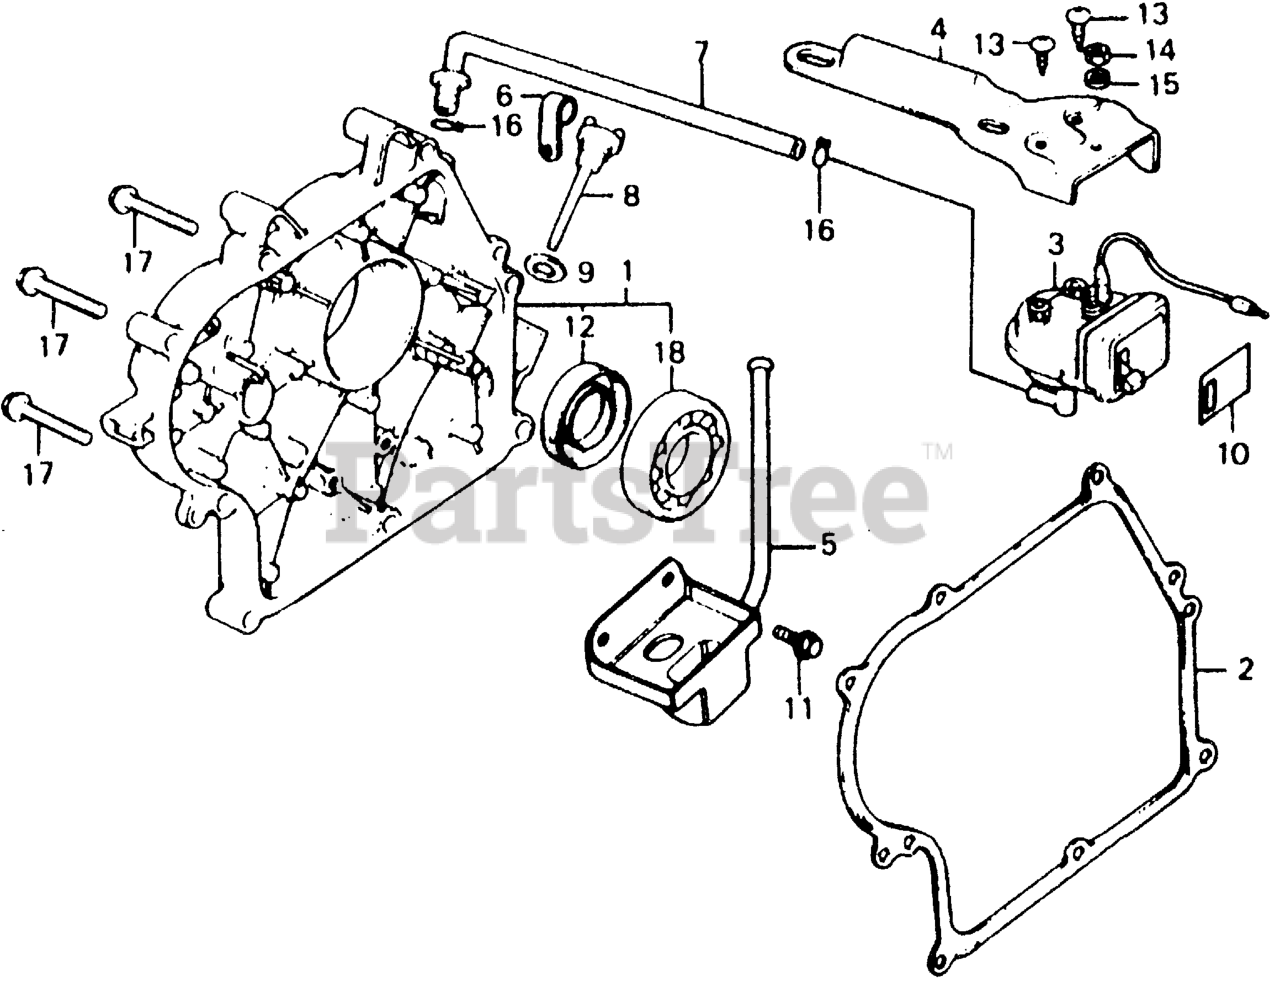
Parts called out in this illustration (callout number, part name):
1	COVER, CRANKCASE (WKZ-TYPE)
2	GASKET, CASE COVER
3	SWITCH ASSY., UNIT
4	BRACKET, UNIT SWITCH
5	CUP, OIL
6	CLAMP, TUBE
7	TUBE, OIL ALERT
8	CAP, OIL FILLER
9	GASKET, OIL FILLER CAP Use from Engine SN 1391010.
10	MARK, CAUTION (ENGLISH/FRENCH)(SPANISH)
11	BOLT, FLANGE (6X16)
12	OIL SEAL (30X45X8)
13	SCREW, TAPPING (5X10)
14	NUT, HEX. (5MM)
15	WASHER, SPRING (5MM)
16	CLIP, TUBE (C11)
17	BOLT, FLANGE (8X40)
18	BEARING, RADIAL BALL (6206)
